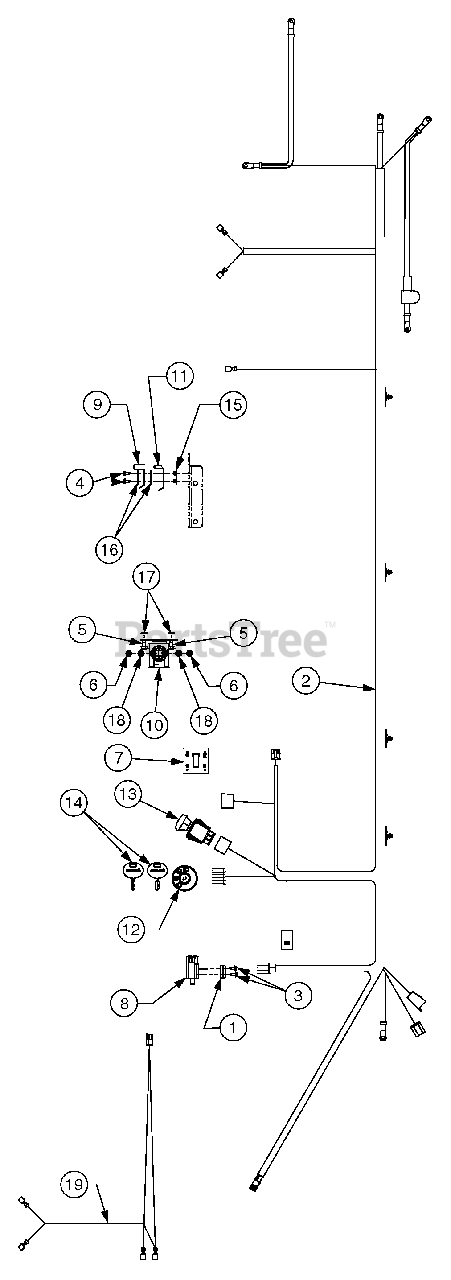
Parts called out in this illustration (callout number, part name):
1	Plate, Switch
2	Harness Assembly
3	Screw, Hx. Wash. Hd. Tapp, 10-16 x .5
4	Screw, Hx. Wash. Hd. Tapp, 8-18 x .5
5	Screw, Hx. Wash. Hd. Tapp, 1/4-20 x .5
6	Nut, Hex, 1/4-20, GR5
7	Indicator/ Meter Hour
8	Switch, Interlock
9	Switch, Outer Seat Spring
10	Solenoid, Starter, 12V
11	Switch, Inner Seat Spring
12	Switch, Key, 4-Position
13	Switch, Electric PTO
14	Key, Switch, Plastic
15	Plate, Insulator Boss
16	Plate, Insulator
17	Washer, Lock, Ext 1/4
18	Washer, Lock, 1/4
19	Harness Assembly, Headlight
